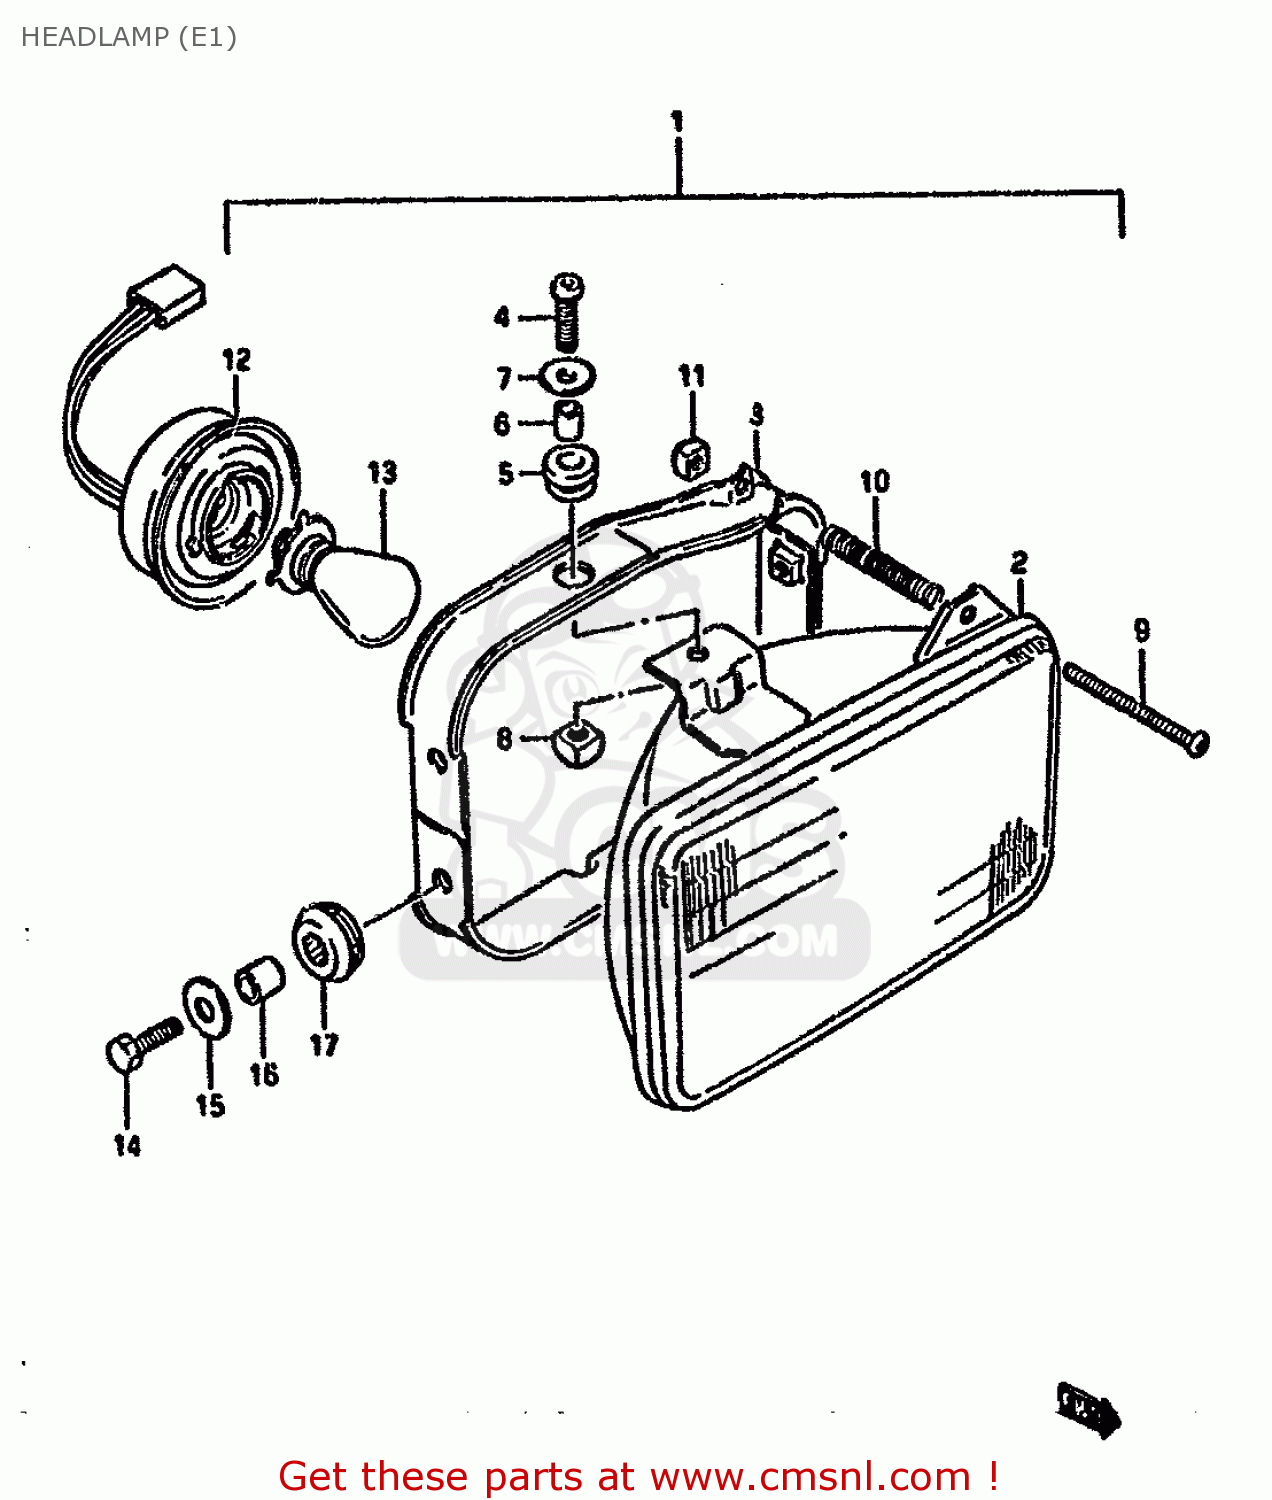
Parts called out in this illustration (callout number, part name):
1	HEADLAMP ASSY
2	UNIT
3	HOUSING
4	SCREW 5X20
5	CUSHION
6	SPACER
7	WASHER
8	NUT
9	SCREW,HEADLAMP ADJUST
10	SPRING
11	NUT
12	SOCKET,HEAD LAMP
13	BULB (6V,35/35W)_
14	BOLT
15	WASHER (6.5X20X1.2)
16	SPACER (6.1X9X9)
17	CUSHION
